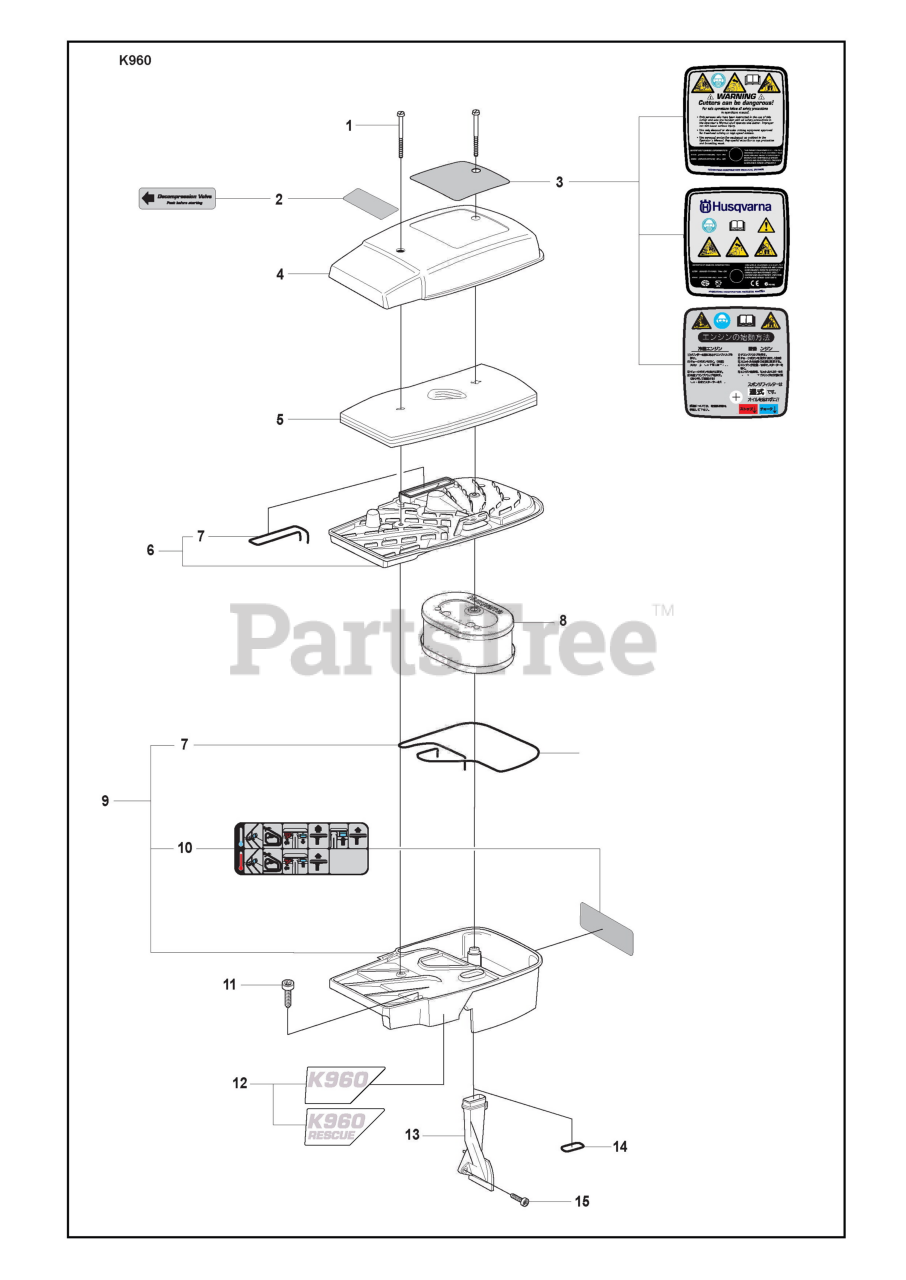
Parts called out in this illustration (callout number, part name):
3	Label
4	Air Filter Cover
6	Filter Bottom
8	Air Filter
9	Cylinder Cover Assy
12	Label
13	Air Nozzle
